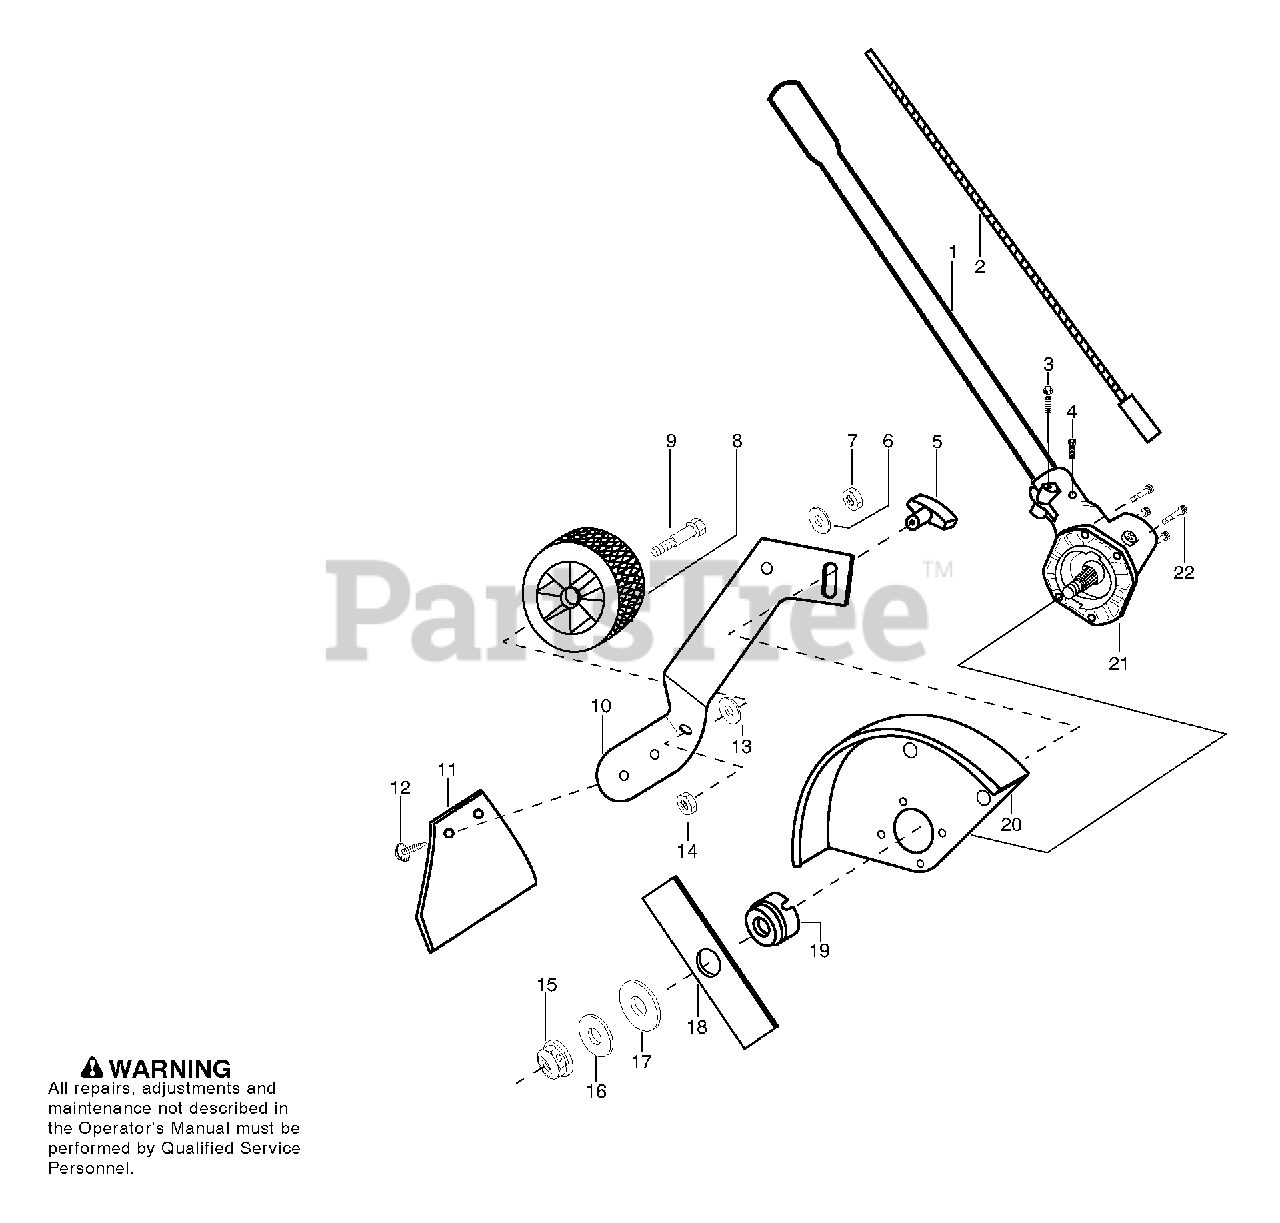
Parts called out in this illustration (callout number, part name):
1	Kit- Driveshaft
4	Screw-Alignment
8	Wheel-4" (rubber)
9	Bolt-Shoulder Axle
10	Bracket-Wheel Adjustment
11	Kit-Mud Flap
12	Fastener-Mud Flap
15	Nut-Flange (L.H.)
16	Washer-Belleville
17	Washer-Flat
18	Blade-7.5"
20	Kit-Edger Guard
21	Kit-Edger Gearbox
